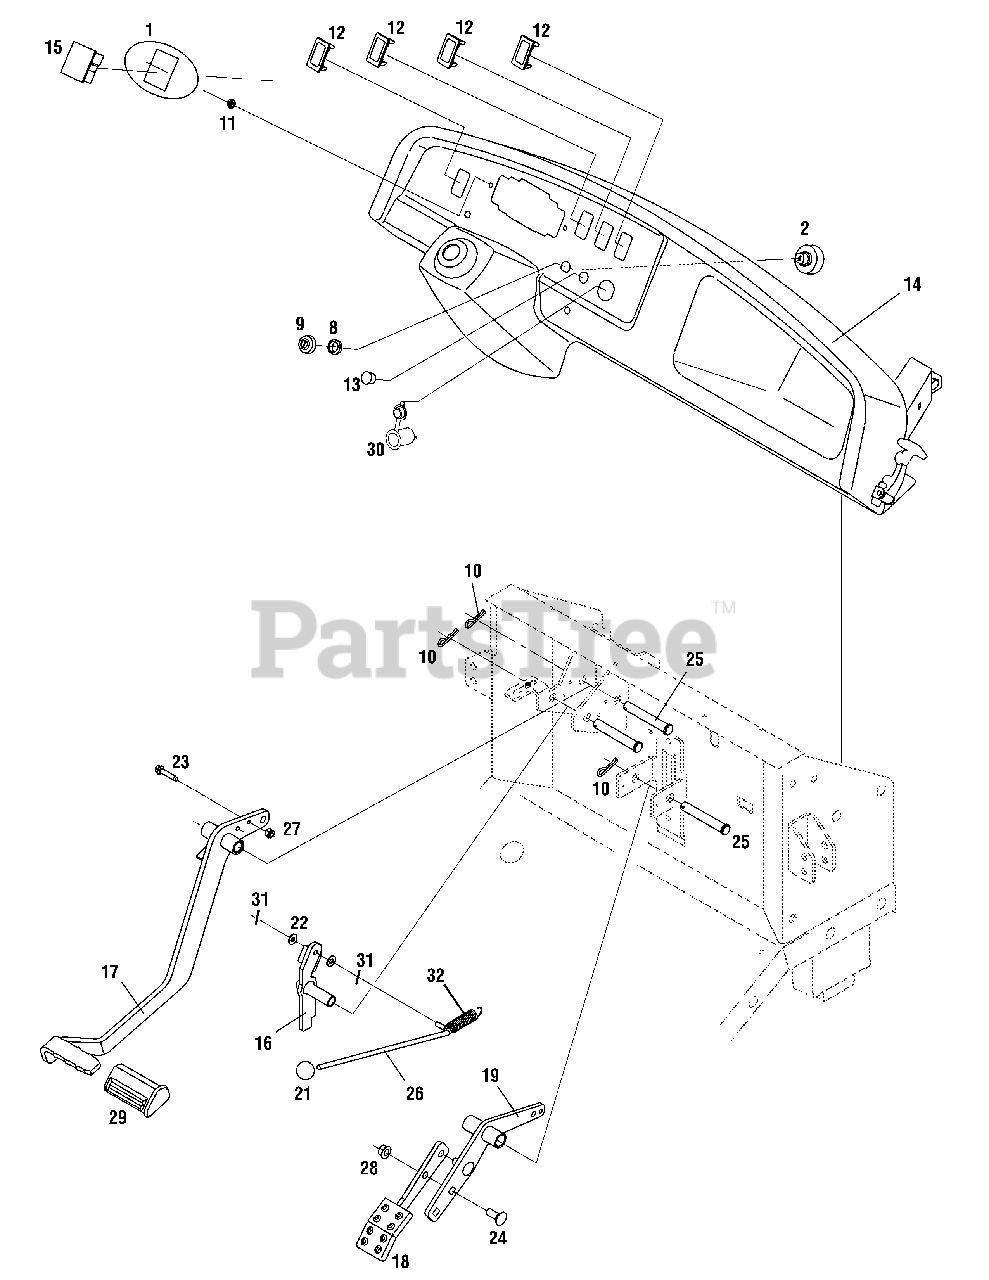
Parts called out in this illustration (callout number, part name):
1	Instrument Cover
2	Switch, Key
8	Nut, Ignition Switch, 5/8-32
9	Cap, Ignition Switch
10	Internal Cotter Pin
11	Nut, Retainer, 1/8
12	Switch Panel
13	Plug, Horn Switch
14	Dash Panel
15	Hour Meter
16	Lever, Parking Brake
17	Pedal Assembly, Brake
18	Pedal Assembly, Throttle
19	Pedal Arm Assembly, Throttle
21	Knob, Ball
22	Washer, Flat .25 x .630 x .0515
23	Screw, Self-Tapping, 1/4-20x1.25
24	Bolt, Carriage, 3/8-16 x 1.0
25	Pin, Clevis.50 x 3.25
26	Rod, Brake Lock
27	Nut, Hexlock,` 1/4-20 GR 8
28	Nut, Flange Lock, 3/8-16
29	Pad, Brake Pedal
30	Rcptl, Pwr, 12V
31	Pin, Cotter, 1/16
32	Spring, Extension, .637 x 2.972
